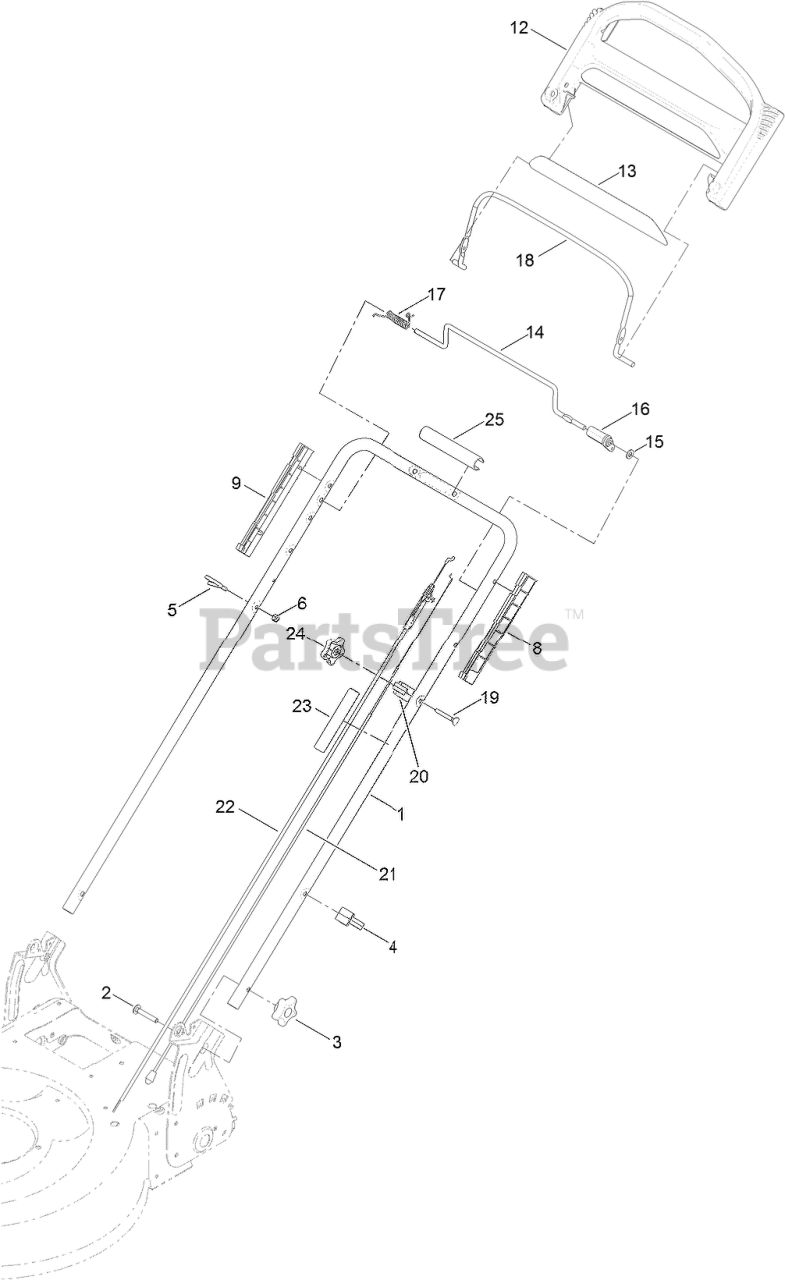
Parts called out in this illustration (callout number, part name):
2	Screw-CARR
3	KNOB-HANDLE
4	GUIDE-CABLE
5	GUIDE-ROPE
6	NUT-LOCK, NI
8	GUIDE-LH
9	GUIDE-RH
12	HANDLE-CONTROL
14	BAR-CONTROL, TRACTION
15	WASHER-PLAIN
16	LEVER-TRACTION
17	Spring-Torsion
18	Bail-Brake
19	SCREW
20	ANCHOR-CABLE
21	CABLE-TRACTION
22	CABLE-BRAKE
23	DECAL-TRACTION, ADJUST
24	KNOB-HANDLE, LOCKING
25	COVER-HANDLE
